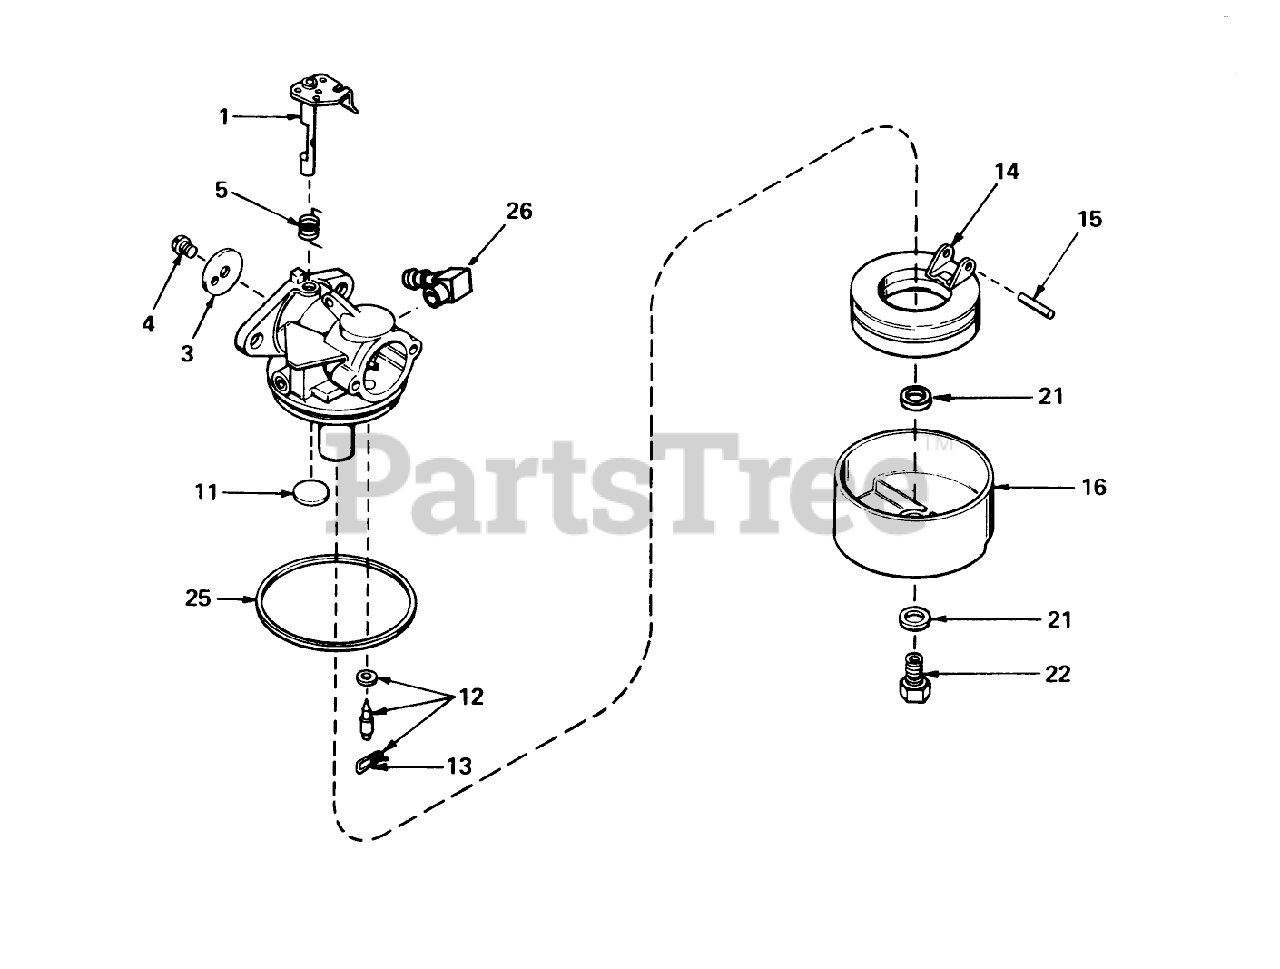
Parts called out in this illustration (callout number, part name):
1	Throttle Shaft and Lever ASM
3	Throttle-Shutter
4	Screw-Shutter
5	Spring, Return
11	Plug-Welch, Atmospheric Vent
12	Inlet Needle, Seat Clip Assy. (Incl. No. 13)
13	Clip-Spring
14	Float,Carburetor
15	Shaft-Float
16	Bowl Float
21	Gasket-Bowl
22	Nut-Float Bowl
25	O Ring-Bowl, Float
26	Fitting-Fuel
